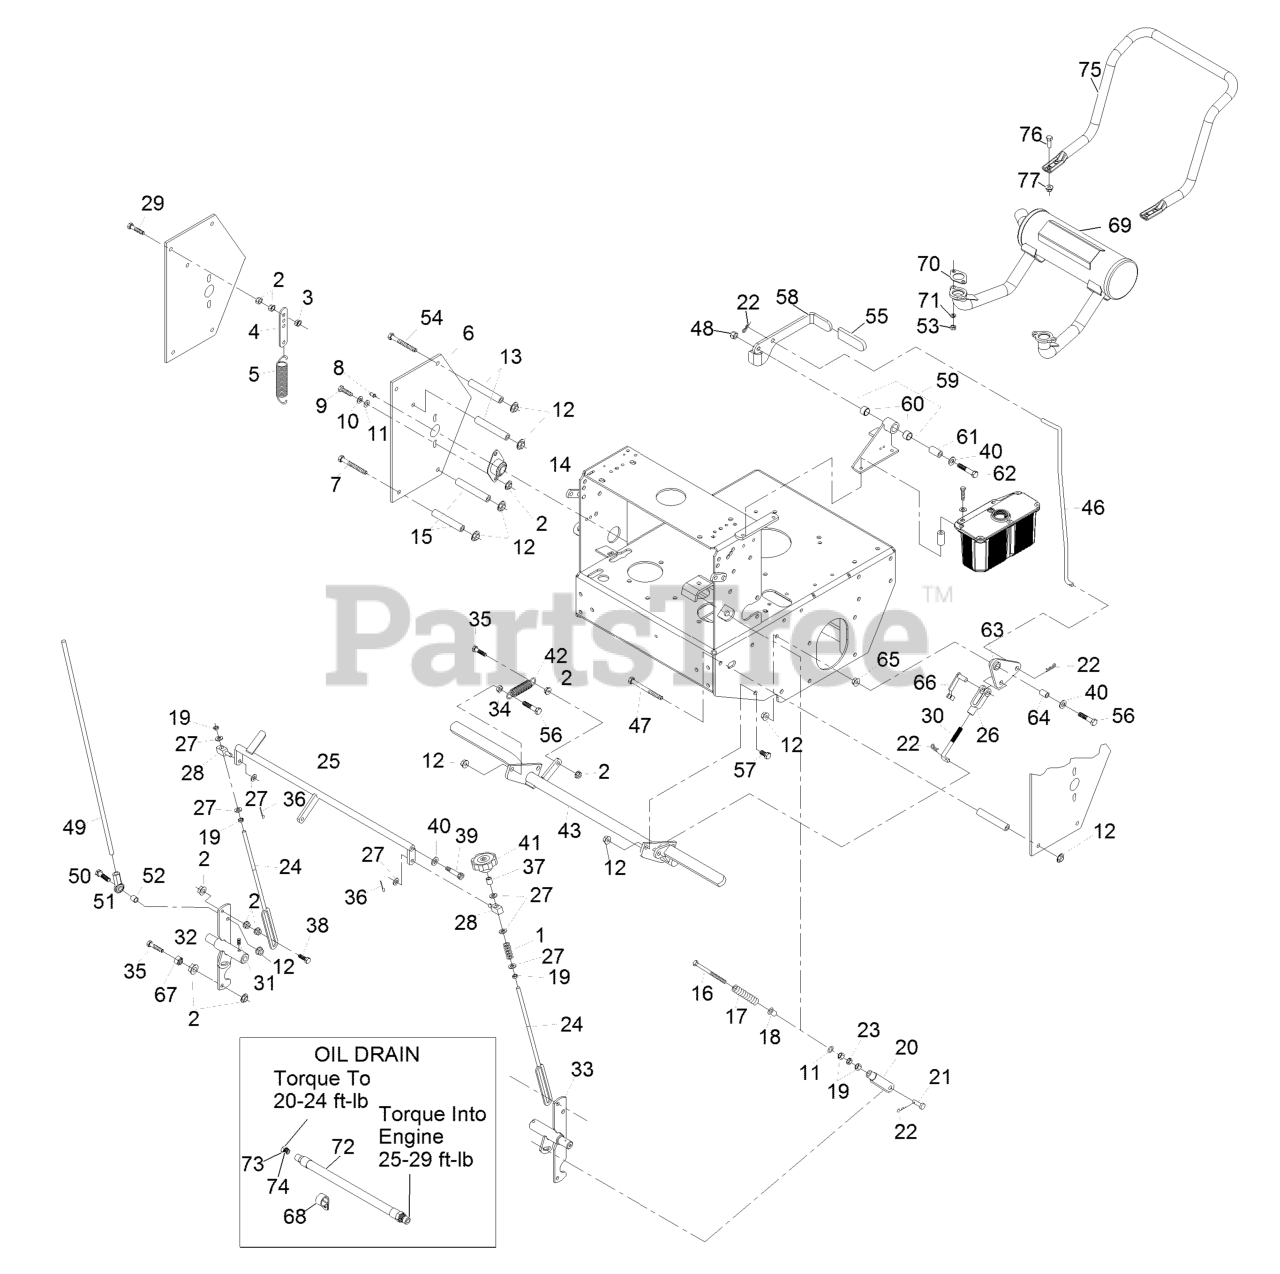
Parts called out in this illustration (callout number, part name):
1	SPRING-COMPRESSION
3	NUT-LOCK, NI
4	TAB-SPRING, EXTENSION
5	SPRING-EXTENSION
6	SHIELD-CONTROL
7	SCREW-HH
8	FITTING-GREASE
9	SCREW-HH
10	WASHER-LOCK
11	WASHER-FLAT
12	NUT-HHF, WHIZ
13	SPACER-SHIELD
14	BEARING-FLANGE, SIDE
15	SPACER-SHIELD
16	BOLT-RETURN, NEUTRAL
17	SPRING,COMPRESSION (NEUT)
18	BUSHING-FLANGED
19	NUT-HEX
20	YOKE-ADJUSTABLE
21	PIN-CLEVIS
22	PIN-COTTER
23	NUT-JAM
24	LINK-CONTROL, SPEED
25	CRANK-CONTROL, SPEED
26	YOKE-LINKAGE, BRAKE
27	WASHER-PLAIN
29	BOLT-TAP, HH
30	LINKAGE-LOWER
31	SCREW-SET
32	SHAFT-CONTROL, LH
33	SHAFT-CONTROL, RH
34	NUT-JAM
35	SCREW-HH, SPECIAL
36	PIN-COTTER
38	SCREW-HH
39	SCREW-HSH
40	WASHER-FLAT
41	KNOB-TRACKING
42	SPRING-IDLER
46	LINKAGE,UPPER- TTHP
47	SCREW-HH
48	NUT-LOCK, NI
49	LINK,DRIVE (PLTD)
50	SCREW-HH
51	JOINT-BALL END, LH
52	SPACER-TUBE, PUMP LINK
54	SCREW-HH
55	GRIP-LEVER
56	SCREW-HH
57	SCREW-HH
58	LEVER,PARK BRK W/DECAL
59	BRACKET ASM
60	SLEEVE-BUSHING
61	BUSHING-PIVOT
62	SCREW-HH
63	BELLCRANK ASM
64	BUSHING-PLASTIC
66	PIN-SPRING, CLEVIS
67	NUT-JAM
68	CLIP-LOOM
69	MUFFLER-HORIZONTAL
70	GASKET-EXHAUST
71	WASHER-LOCK
72	ASM, ENGINE OIL DRAIN HOS
73	PLUG-HH
74	O-RING
75	GUARD-MUFFLER
76	SCREW-HH
77	NUT-HF, NI
